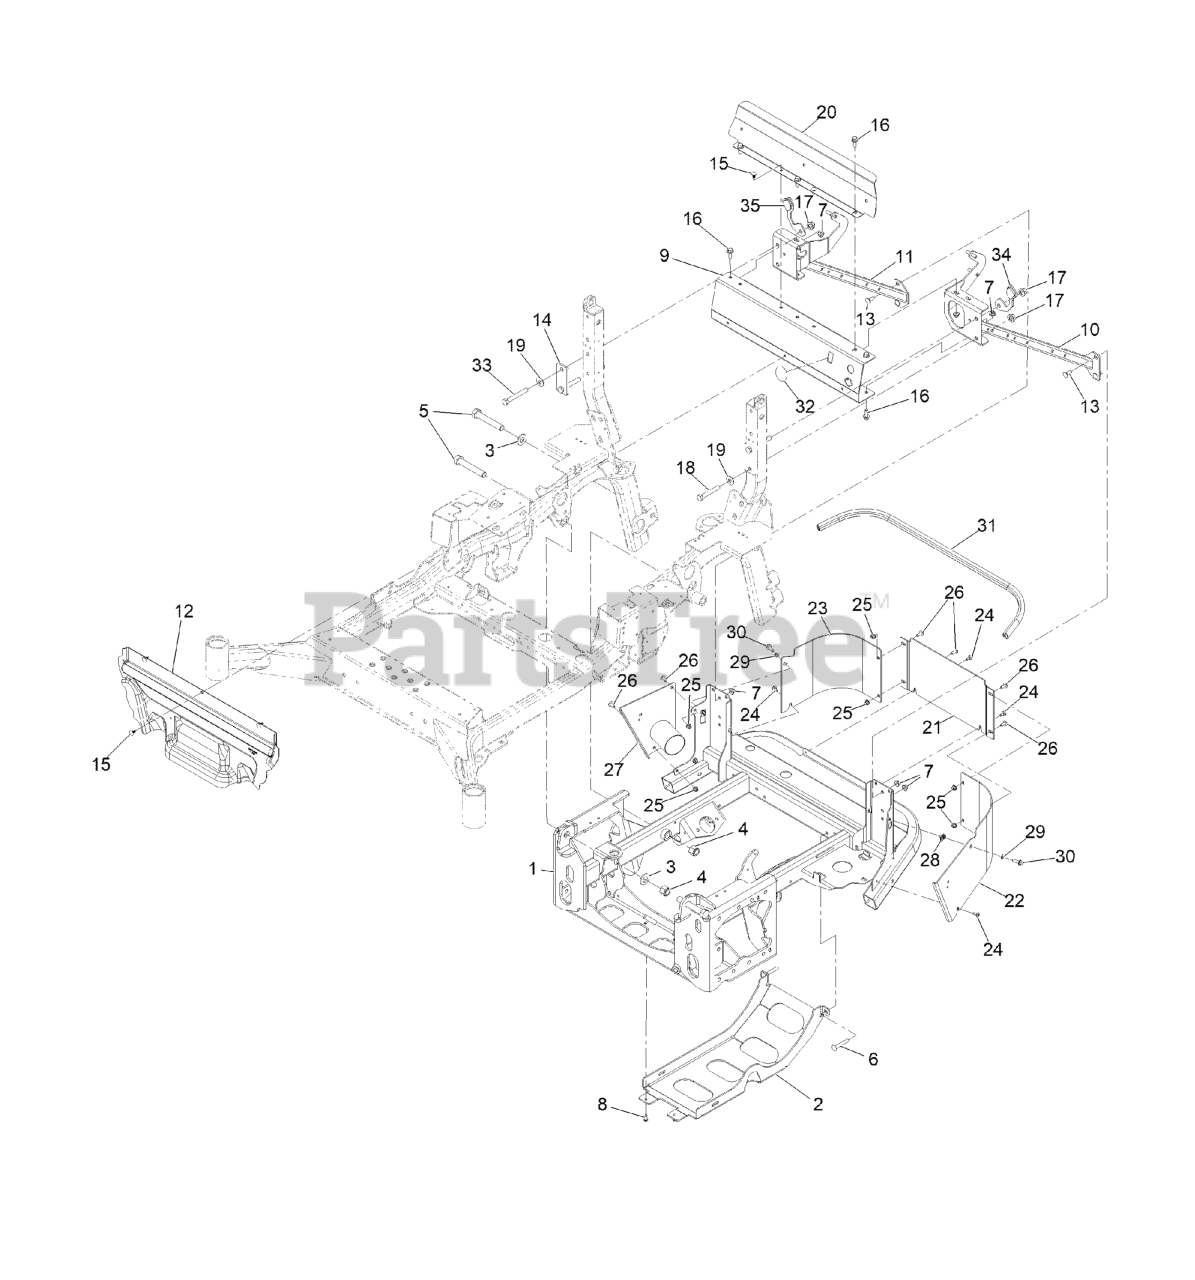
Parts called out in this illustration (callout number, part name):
1	FRAME-POWER
2	PLATE-SKID
4	NUT-LOCK, NI
5	SCREW-HH
6	SCREW-CARR
7	NUT-HF, NI
8	SCREW-BHTF
9	CHANNEL-CROSS
10	BRACE-ROPS, LH
11	BRACE-ROPS, RH
12	PANEL-DEFLECTOR, HEAT
13	SCREW-CARR
14	PLATE-SPACER
15	PLUG-PLASTIC
16	SCREW-HHF
17	Nut-Lock 1/2-13
18	SCREW-HH
19	WASHER-SPRING
20	SHIELD-AIR
21	PLATE-BUMPER, CENTER
22	PLATE-BUMPER, LH
23	PLATE-BUMPER, RH
24	SCREW-SHOULDER
25	NUT-HF, NI
26	SCREW-TORX
27	PLATE-EXHAUST
29	WASHER-BELLEVILLE
30	SCREW-HHF
31	SEAL-BULB
32	DECAL-COVER
33	SCREW-HH
34	STOP-ROPS
35	STOP-ROPS
